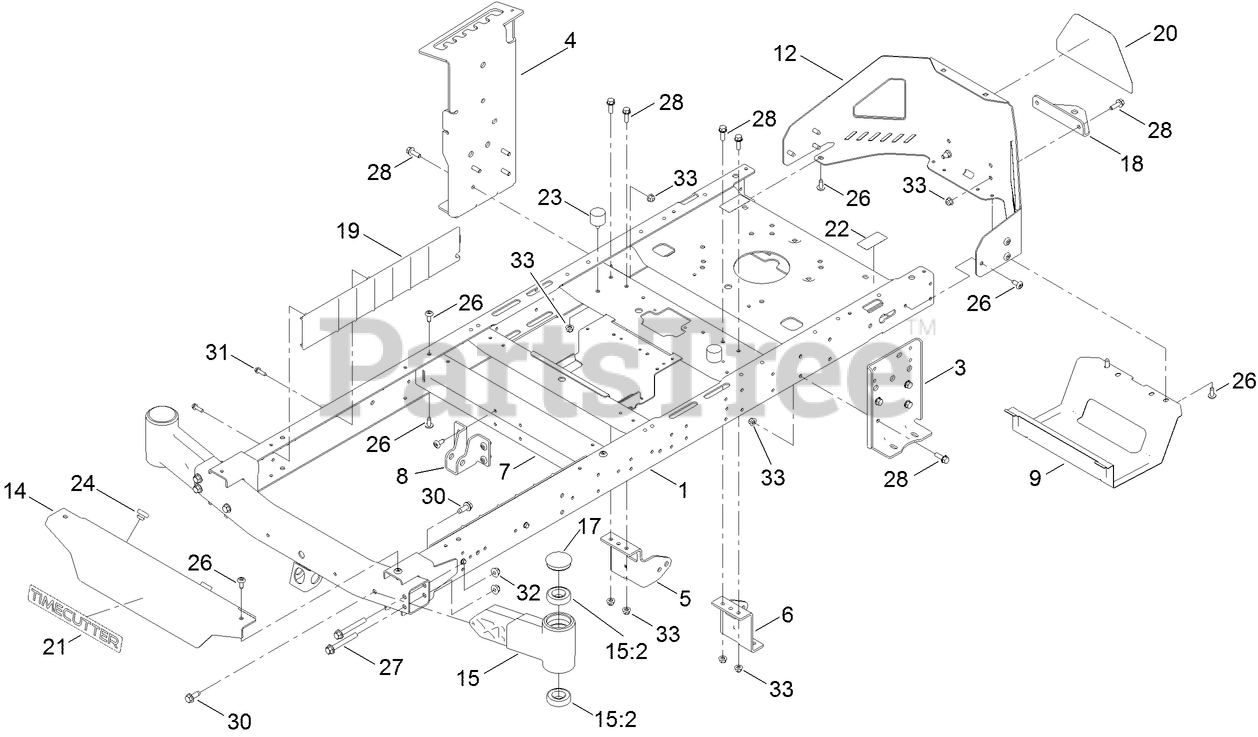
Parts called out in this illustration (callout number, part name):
1	FRAME ASSEMBLY
3	PLATE-MOUNT, HYDRO
4	PLATE-MOUNT HYDRO, RH
5	MOUNT-HYDRO, FRONT (RIGHT)
6	MOUNT-HYDRO, FRONT (LEFT)
7	BRACE-CROSS, LOWER
8	BRACKET-MOUNT DAMPER, LOWER
9	GUARD-MUFFLER
12	GUARD-ENGINE
14	FOOTREST
15	AXLE STUB ASM
15:2	BEARING-BALL
17	CAP-GREASE
18	BRACKET-HITCH
19	GUARD-RAIL
20	DECAL-TIMECUTTER
21	DECAL-TIMECUTTER
22	DECAL-BYPASS
23	BUMPER-RUBBER
24	BUMPER-RUBBER
27	SCREW-HHF
28	SCREW-HHF
30	SCREW-HWH
31	SCREW-PLASTITE, HWH
32	NUT-HF, NI
33	NUT-HF
